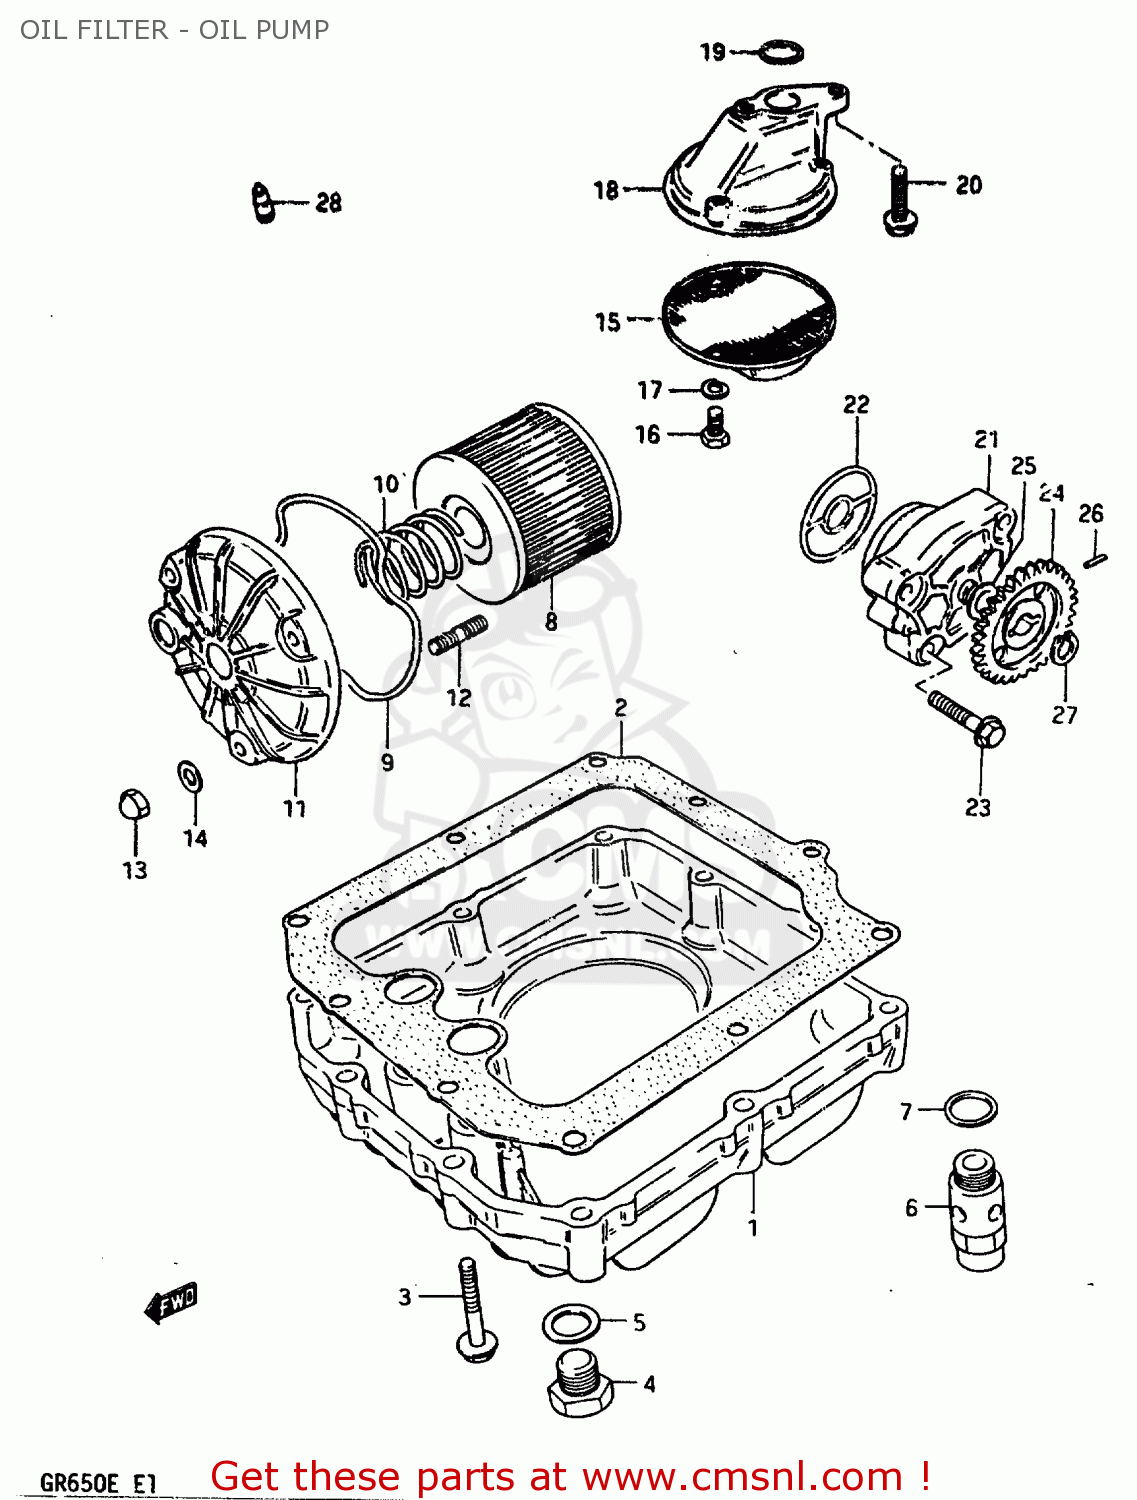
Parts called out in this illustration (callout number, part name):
1	PAN,OIL
2	GASKET,OIL PAN (MCA)
3	BOLT 6X30
4	PLUG
5	GASKET(14X19.2X2) (NAS)
6	REGULATOR ASSEMBLY,ENGINE
7	WASHER
8	FILTER ASSY,ENGINE OIL
9	O RING,OIL FILTER CHAMBER CAP
10	SPRING
11	CAP,OIL FILTER
12	STUD 6X20
13	NUT 6MM
14	WASHER
15	STRAINER,ENGINE OIL
16	BOLT
17	LOCK WASHER
18	PROTECTOR,OIL STRAINER
19	O RING(D:3.2,ID:15.8)
20	BOLT,REAR
21	PUMP ASSEMBLY,ENGINE OIL
22	O RING,OIL PUMP
23	BOLT
24	GEAR,OIL PUMP DRIVEN (N
25	SHIM
26	PIN(4X15.8)
27	CIRCLIP
28	VALVE ASSEMBLY,PISTON OIL
